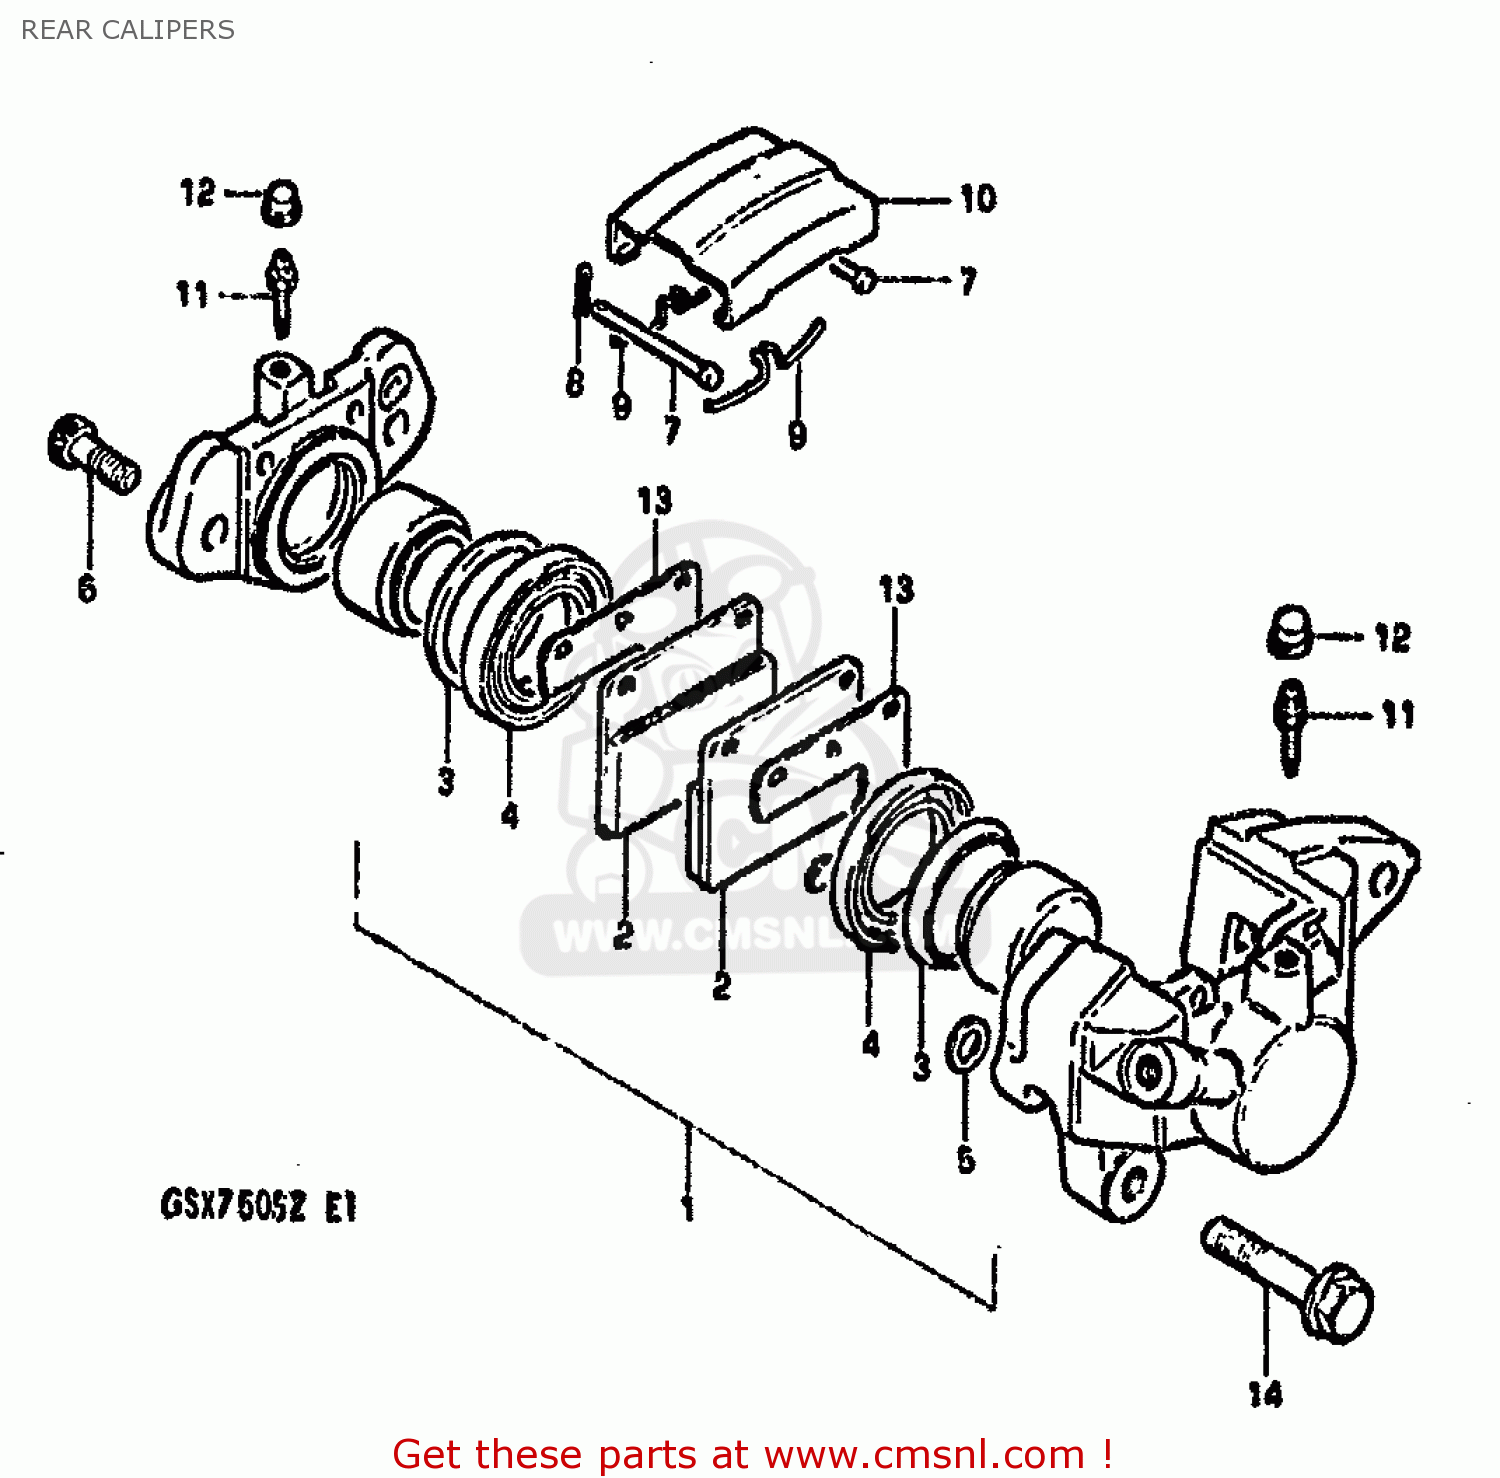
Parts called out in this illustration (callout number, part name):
1	PISTON SET
2	PAD,BRAKE
3	SEAL,PISTON
4	BOOT,PISTON
5	SEAL,PISTON
6	BOLT,HOUSING
7	PIN,PAD
8	CLIP,PAD PIN
9	SPRING
10	COVER,DUST
11	BLEEDER
12	CAP,BREATHER
13	SHIM,RR CALIPER
14	BOLT
